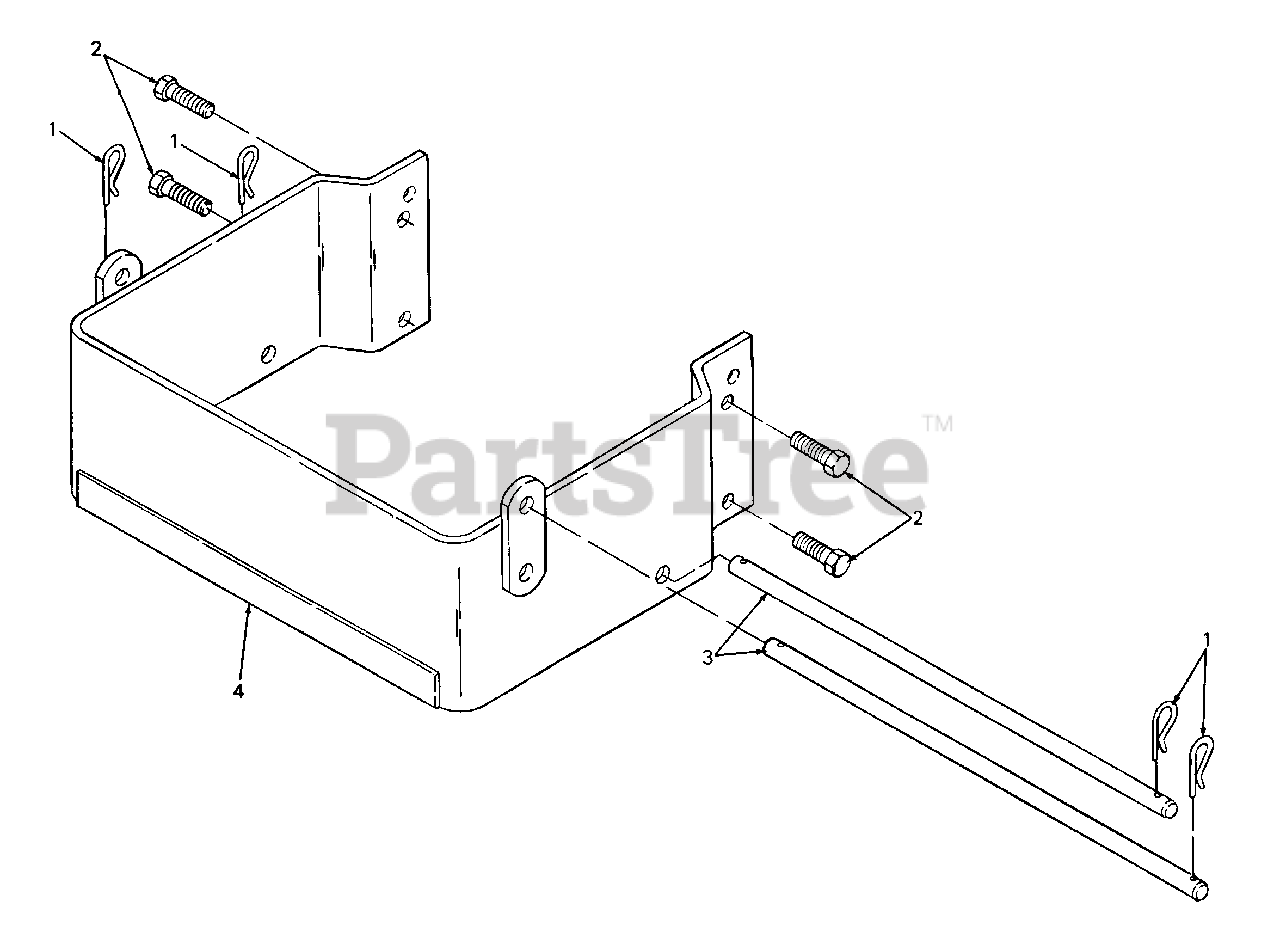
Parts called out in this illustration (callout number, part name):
1	Pin, Internal Cotter
2	Screw, Hex Cap, 3/8-16 X 1.25 Lg GR5
3	Rod, .50 Dia X 15.0 Lg
4	Bracket Assy, Rear Weight
